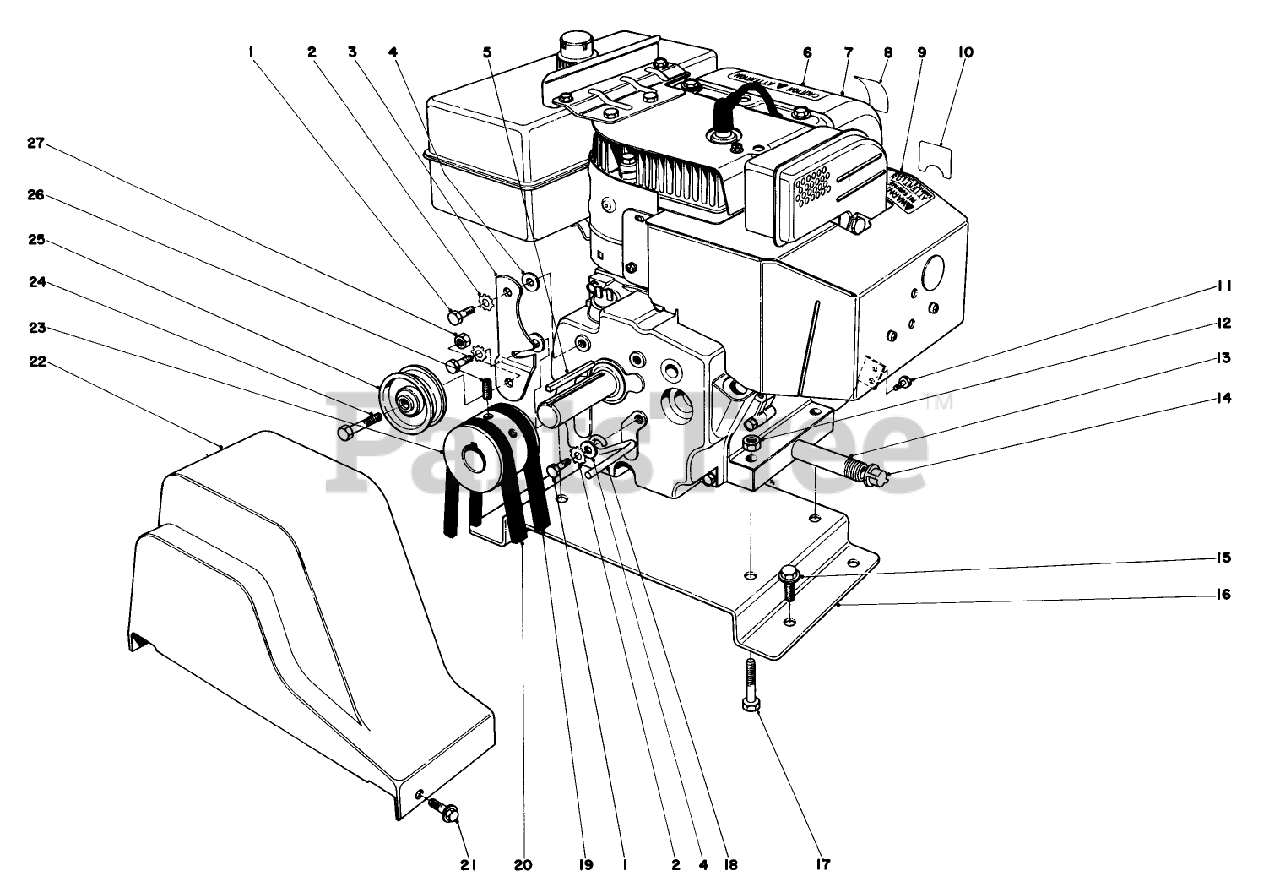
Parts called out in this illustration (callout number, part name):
1	SCREW-HH
2	WASHER-LOCK
4	WASHER-PLAIN
6	CAUTION DECAL
7	Engine
11	SCREW
12	NUT-LOCK, NI
13	NIPPLE-PIPE
14	CAP-PIPE
15	SCREW-HHFTF
17	SCREW-HH
19	V-BELT
20	V-BELT
21	SCREW-HWH
24	SCREW-HH
25	PULLEY-IDLER
